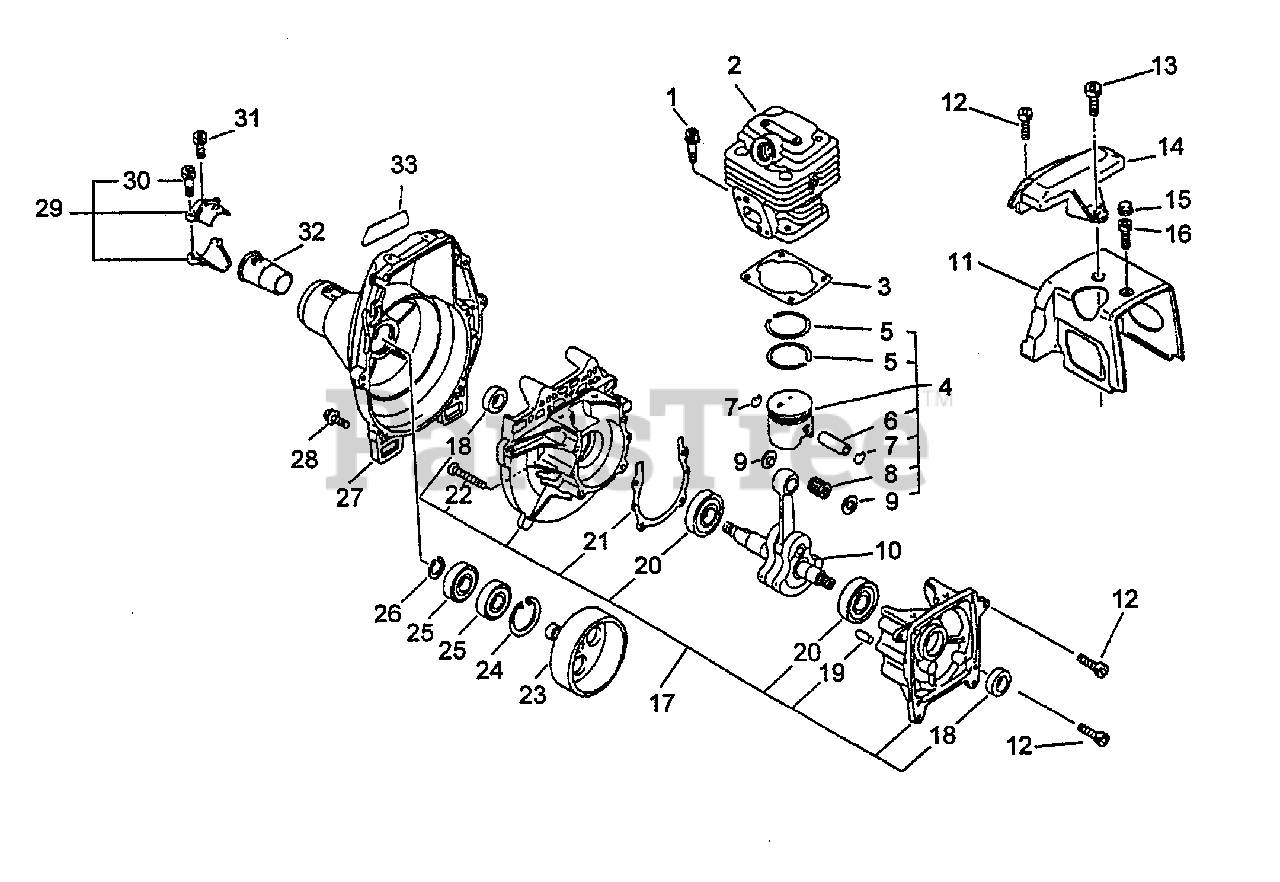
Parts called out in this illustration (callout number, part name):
1	BOLT 5×20
2	CYLINDER
3	GASKET, CYLINDER
4	PISTON KIT
5	RING, PISTON
6	PIN, PISTON
7	RING, RETAINING
8	BEARING, NEEDLE 9
9	WASHER, THRUST
10	CRANKSHAFT ASSY
11	COVER, ENGINE
12	BOLT 4×14
13	BOLT 5×16
14	GUARD, TOP
15	SCREW - SOCKET HEAD CAP
16	BOLT 5×12
17	CRANKCASE KIT
18	SEAL, OIL 12
19	PIN, LOCATING 4
20	BEARING, BALL - 6201 C3
21	GASKET, CRANKCASE
22	BOLT 5×30
23	DRUM, CLUTCH
24	RING, SNAP 28
25	BEARING, BALL 6001
26	RING, RETAINING - 12
27	COVER, FAN
28	BOLT 5×20
29	HOLDER KIT
30	BOLT 5×25
31	BOLT 5×12
32	CUSHION 28
33	LABEL - MODEL SRM-3400
